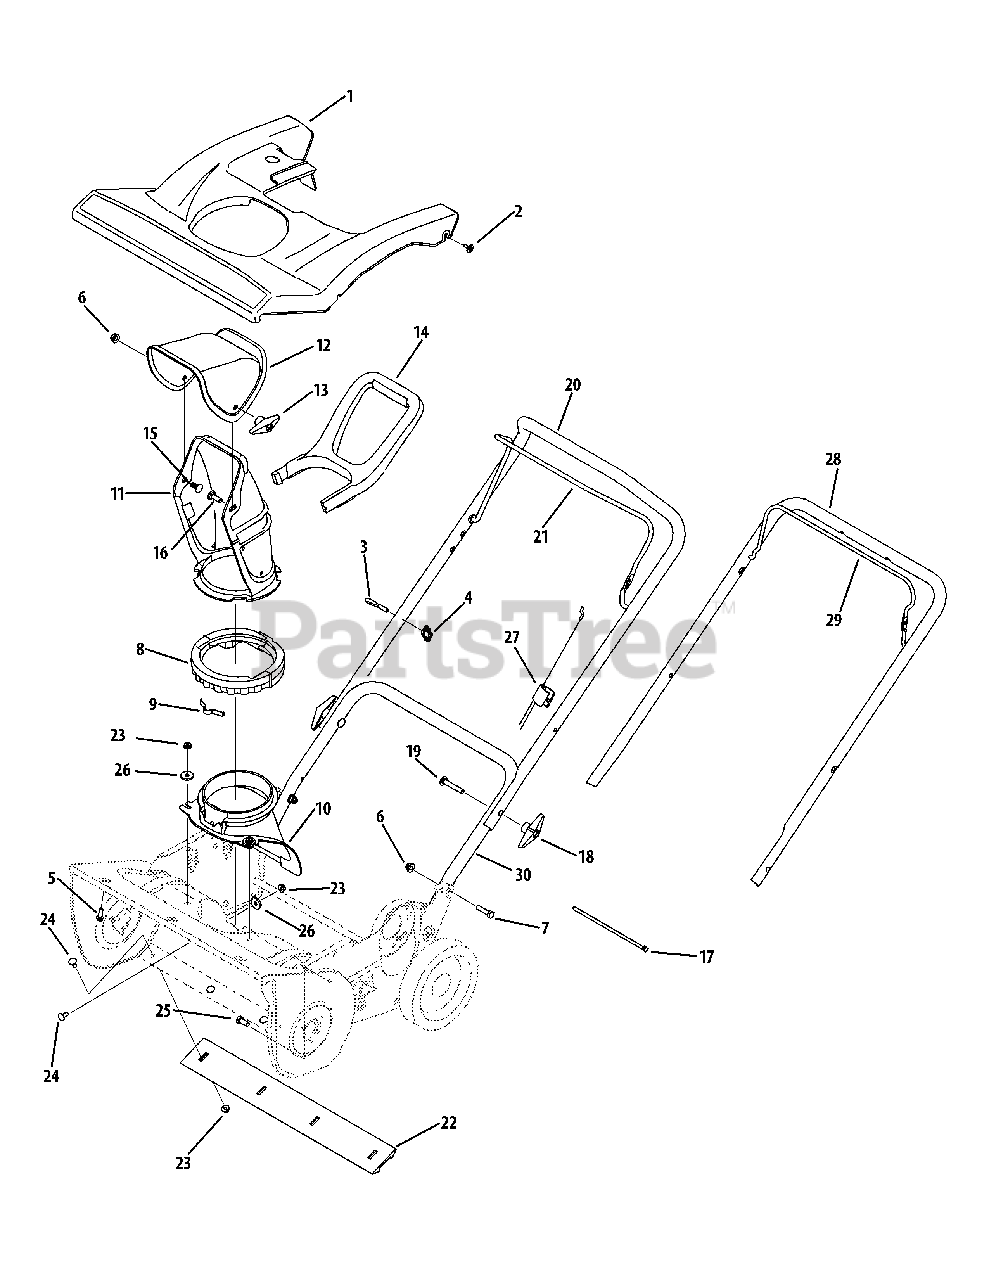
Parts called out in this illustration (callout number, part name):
1	Shroud Ass’y (Models w/electric start)
2	Hex Wash B-Tapp Scr #10 x .62" Lg.
3	Eyebolt 1/4-20
4	Handle Knob Assembly
5	Hex Tapp Scr 1/4 x .75" Lg.
6	Flange Locknut 5/16-18 Gr. F, Nylon
7	Hex Flg. Screw 5/16-18 x 1.25
8	Lower Chute Ring
9	Chute Adjustment Spring
10	Chute Adapter 5" Dia
11	Lower Chute 5" Dia
13	Handle Knob Assembly
15	Carriage Bolt 5/16-18 x .75
16	Carriage Screw 5/16-18 x 1.0
18	Handle Knob Assembly
19	Carriage Bolt 5/16-18 x 2.0 Gr. 5
23	Hex L-Flanged Nut 1/4-20 Gr. F Nylon
24	Carriage Bolt 1/4-20 x .62
25	Hex Screw 5/16-18 x .75
26	Flat Washer .25 ID x .93 OD x .125
27	Control Cable
